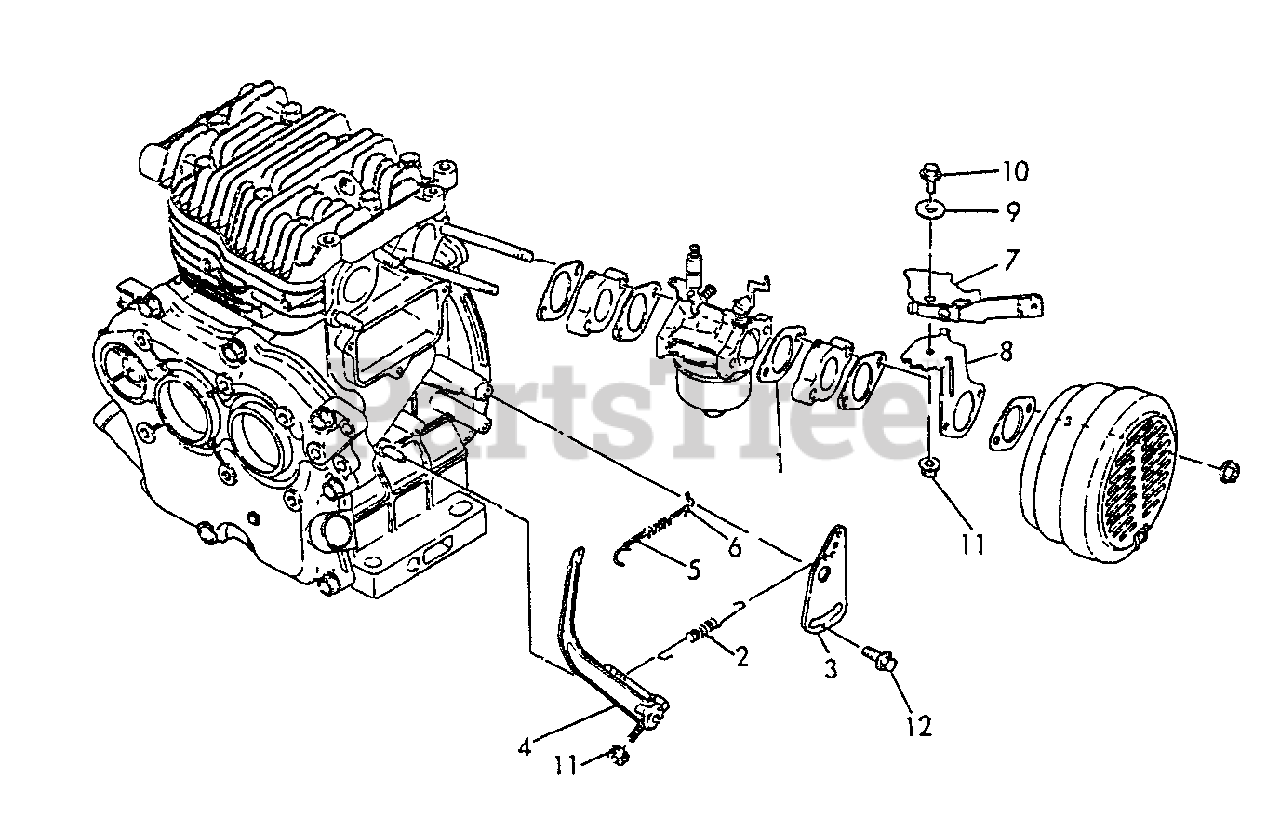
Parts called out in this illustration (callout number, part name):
1	GASKET, INTAKE
2	SPRING, REGULATOR
3	HANDLE, REGULATOR
4	LEVER, GOVERNOR
5	LINK, THROTTLE
7	LEVEL ASSY
8	BRACKET, LEVER
9	COLLAR
10	BOLT - 6X12 -- PLATED
11	NUT - 6 -- FLANGE
12	BOLT - 6X8 -- PLATED
